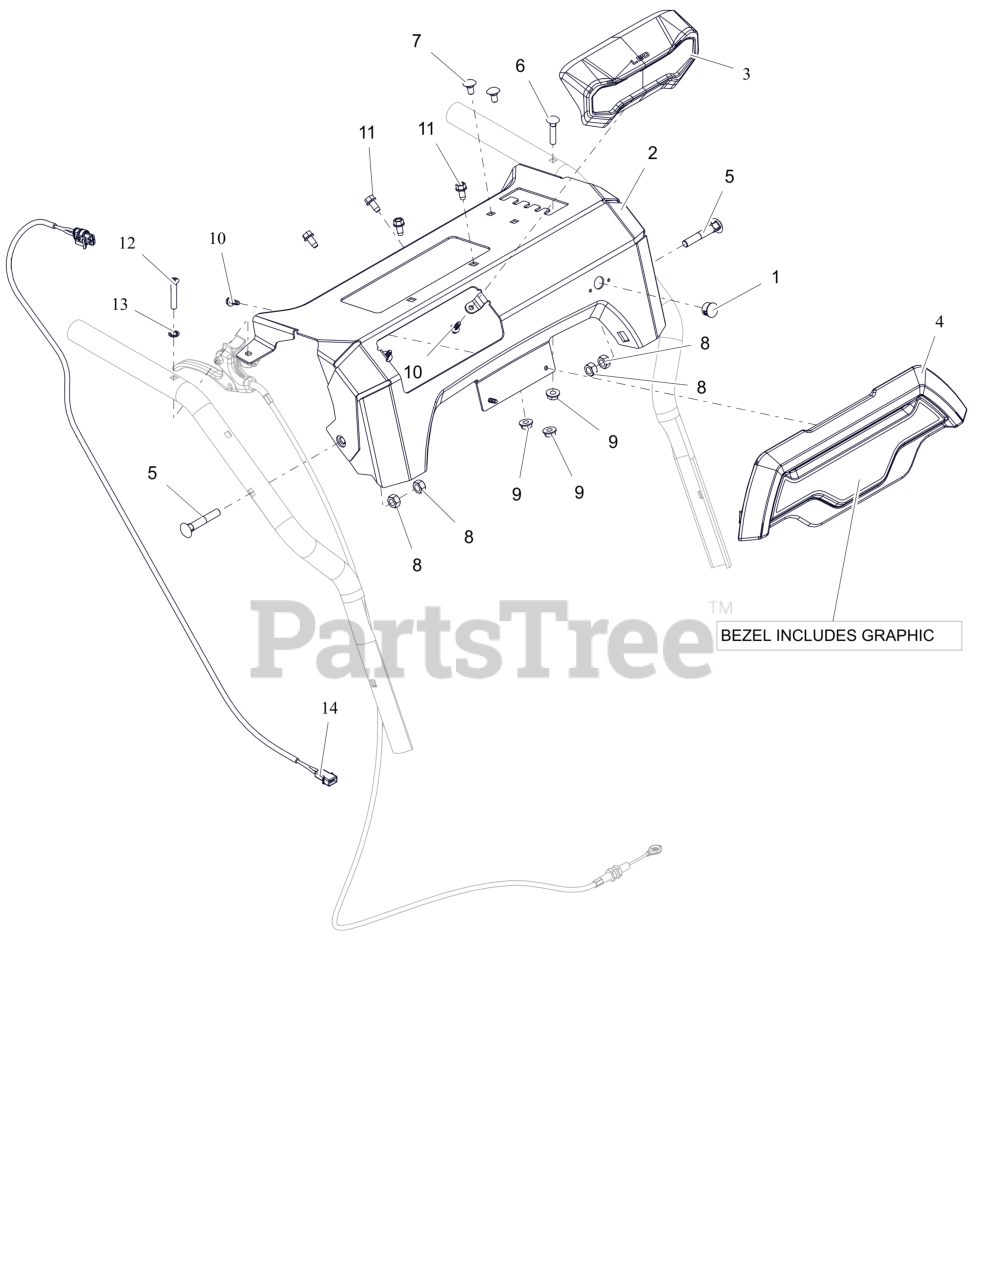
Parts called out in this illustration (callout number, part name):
1	HOLE PLUG, PLASTIC .56 HOLE
2	PANEL, DASH - COMPACT
3	HEADLIGHT ASM- LED
4	BEZEL, SMALL - COMPACT
5	BLT-RDHDXLSQNK .31-18X2.0 G5YZ
6	BLT-RDHDXLSQNK.25-20X1.25 G5ZC
7	BLT, RHSN .25-20X.500 G5 ZCC
8	NUT,LK-CTR .31-18 GA ZCC
9	NUT-LK-CTR-FLG .25-20 ZC120
10	SCR, PLASTIC #10X.50
11	SCR-TAP .25-20X.50 HWH ZCC
12	SCR,OVAL .25-20X1.50 ZCC
13	WSHR-LK-INT .250 TH TYA
14	HARNESS- WIRE - LT
